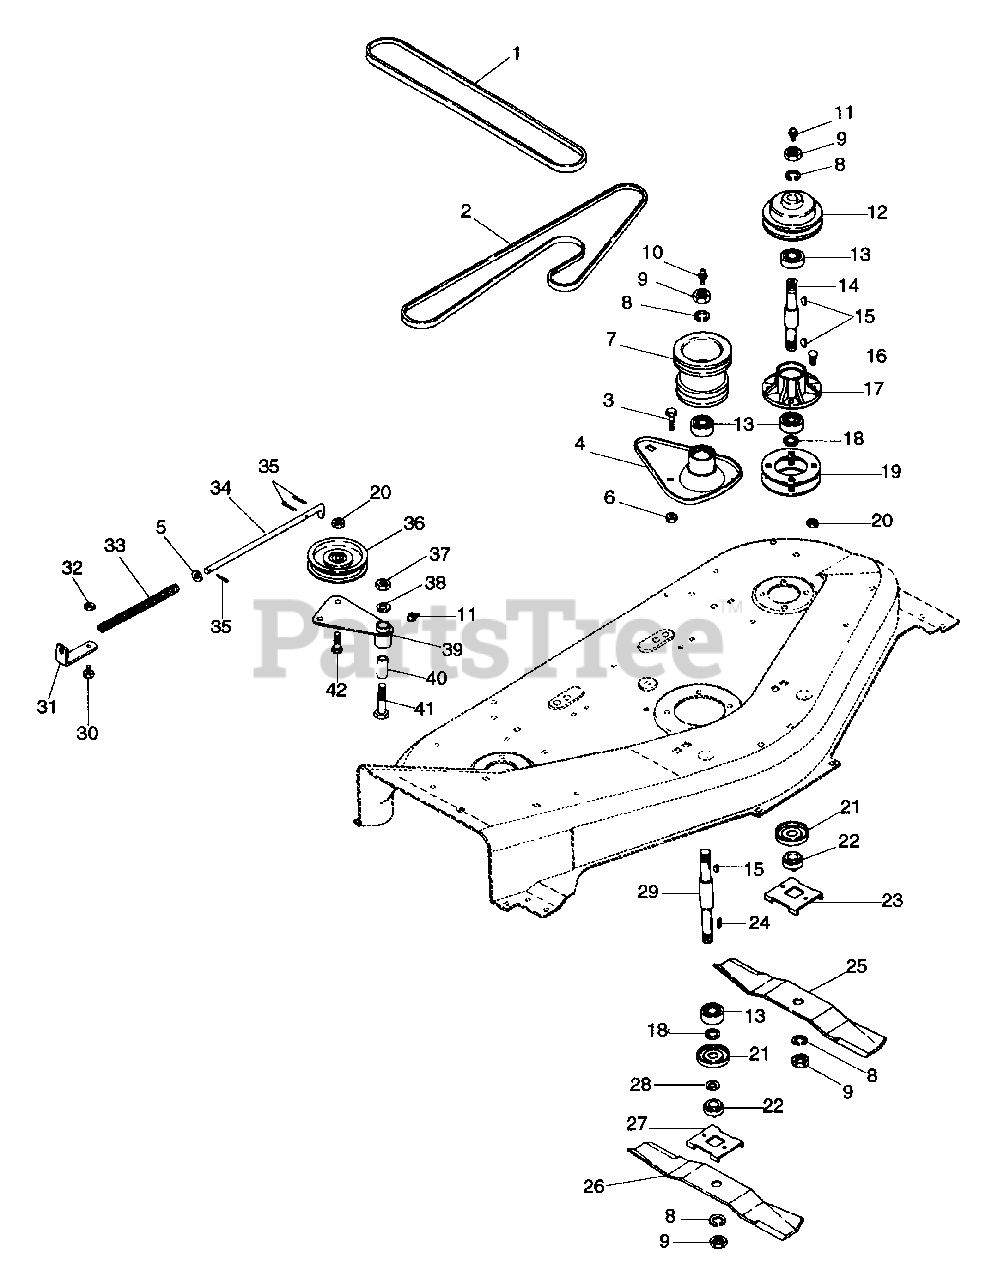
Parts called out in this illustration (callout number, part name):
1	V-BELT, 4L-RAW EDGE
1	V-BELT, HA-WRAPPED
2	V-BELT, HA-WRAPPED
3	BLT-RDHDSQNK .38-16X.62 GR5 PL
4	HOUSING SPINDLE
4	HOUSING,SPINDLE
5	WSHR-FL-STL.406X.812X.065PL
6	NUT-LK-CTR .375-16 GR A PL
7	SHEAVE
8	WSHR-LK .750X.188 MED PL
9	NUT-JAM .75-10 PL
10	GREASE ZERK
11	SPIN DRIVE ZERK FITTING
12	SHEAVE
12	SPINDLE SHEAVE
13	BRG-BALL .750X1.781X.61
14	SPINDLE SHAFT W/ZERK
15	KEY-WDRF .188X.625X.25 SAE 61
16	BLT-RDHDSQNK .375-16X.75 PL
17	SPINDLE HOUSING
17	HOUSING, SPINDLE
18	WSHR-FL-STL .754X1.000X.032
19	SPACER, SPINDLE
19	PLATE
20	NUT-LK-JAM-CTR .375-16 PL
21	BEARING SLINGER
22	RETAINER HUB
23	BLADE TRAY 42
23	BLADE TRAY 48
23	BLADE TRAY
24	KEY-SQ .188X.625X.188 SAE 61
25	BLADE
25	MOWER BLADE 22 1/2
26	BLADE
27	BLADE TRAY 48
28	WSHR-FL-STL .755X1.250X.125
29	SPINDLE SHAFT W/ZERK & KEY
30	BLT-HEX .31-18X.50 GR5
31	BRACKET
32	NUT-LK .312-18 GR A PL
33	SG-COMP .106X.63X 12.0 WLD 62
34	ROD-IDLER SPRING
35	PIN-COTR .09X.75 PL
36	IDLER-FLAT 4.00 X .38 NWHAMSHR
36	IDLER-FLAT 2.75 X .38 DAYCO
37	NUT-LK-CTR .50-13
38	WSHR-FL-STL .505X.880X.072 PL
39	IDLER ARM W/ZERK
40	SPACER .512X.747X.968
41	BLT-HEX .50-13X1.50 PL GR2
42	BLT-BTHD .38-16X1.25 GR5
